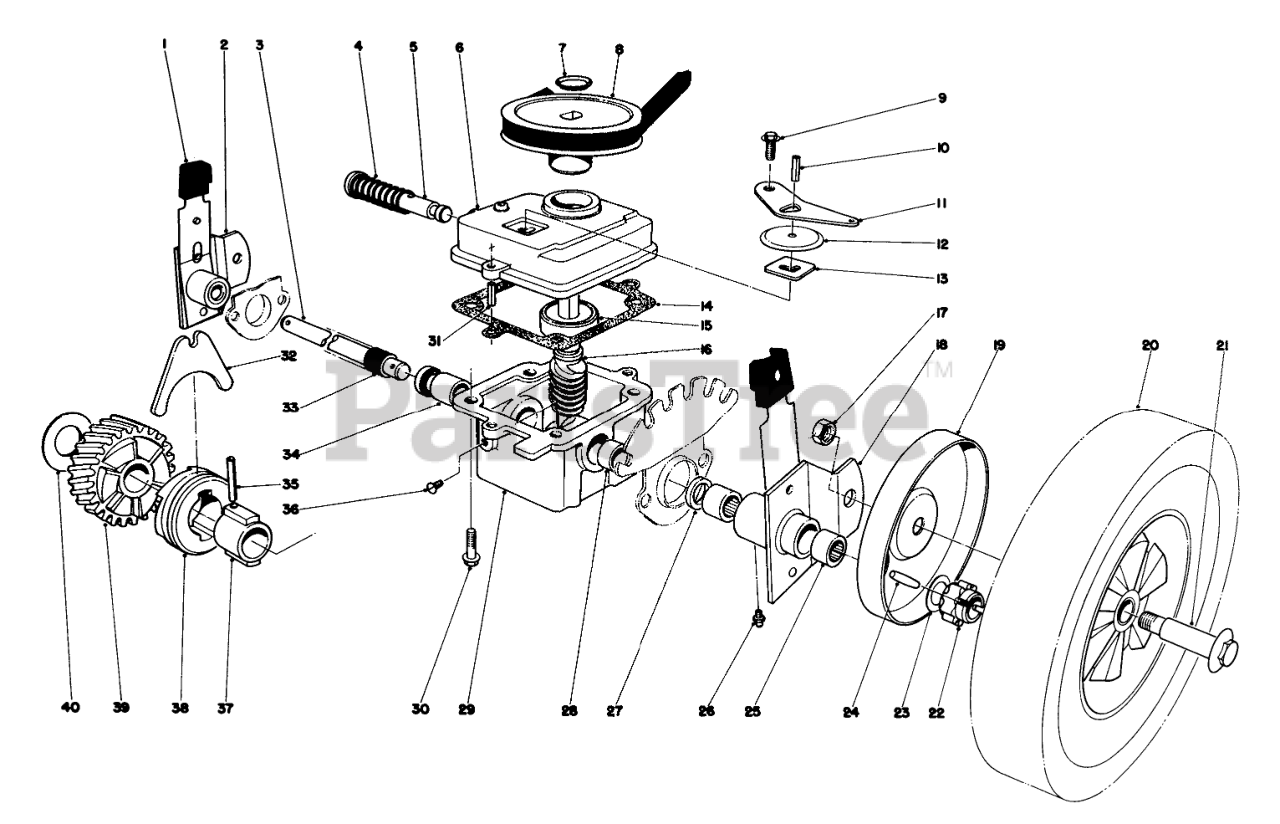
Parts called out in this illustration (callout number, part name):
1	KNOB-ARM
2	Pivot Arm R.H. (Incl. Ref. #25 & 27)
3	Drive Shaft
4	SPRING
5	Shift Rod
6	Case-Upper
7	PUSH-ON 93-3236
8	PULLEY
9	Screw
10	PIN-ROLL
11	SHIFTER ARM
12	TRANS DUST COVER
13	LATCH PLATE
14	GASKET
15	Bearing
16	Shaft-Worm
17	Nut
18	Pivot Arm L.H. (Incl. Ref. #25 & 27)
19	WHEEL COVER
20	Wheel & Tire Assembly
21	BOLT-WHEEL
22	Pinion
23	WASHER-THRUST
24	PIN-GROOVED
25	Needle Baring
26	FITTING-GREASE
27	Seal
28	Bushing
29	Case-Lower (Incl. Ref. #27, 28 & 34)
30	Screw
31	3/16 X 1/2 ROLL PIN
32	SHIFTER FORK
33	Cover-Drive Shaft
34	Bushing
35	COIL PIN
36	NYLON SCREW
37	SLEEVE
38	CLUTCH JAW
39	Helical Gear
40	THRUST WASHER
